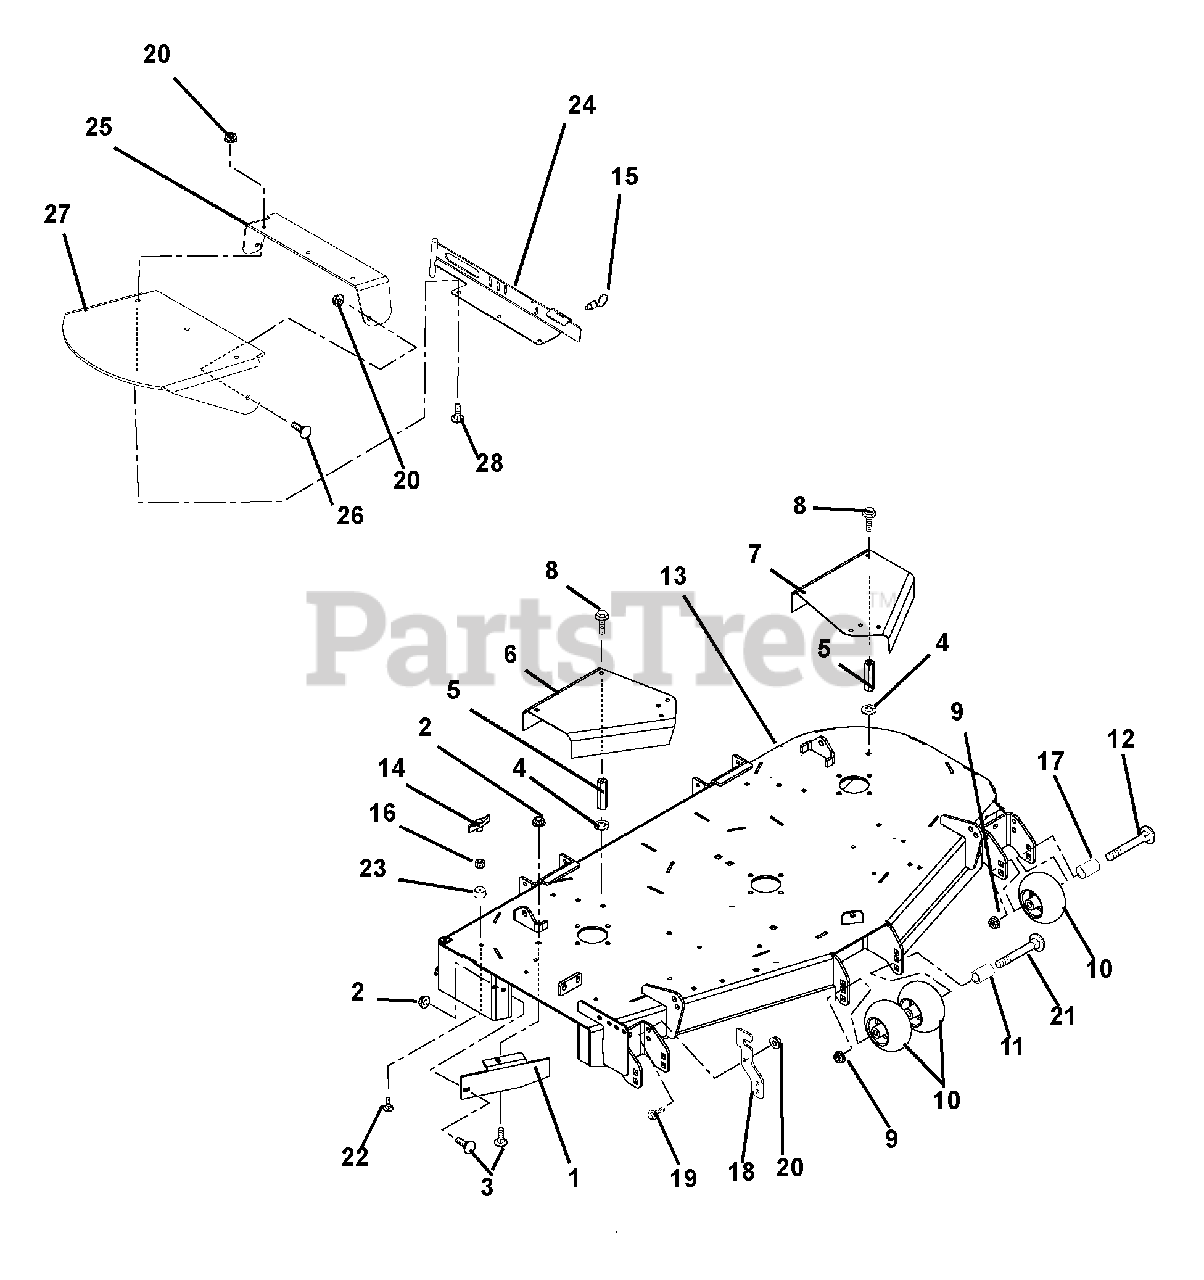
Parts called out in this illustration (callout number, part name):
1	52-in. Discharge Baffle
1	60-in. Discharge Baffle
1	72-in. Discharge Baffle
2	Nut, .31-18 Nyloc Flange
3	Bolt, Round Head Square Neck .31-18 x 1.00 Grade 5
4	Washer, Lock Internal .375
5	Standoff, .38-16 x .50 Self Tapping
6	52-in. Right Hand Spindle Guard
6	60-in. Right Hand Spindle Guard
6	72-in. Right Hand Spindle Guard
7	52-in. Left Hand Spindle Guard
7	60-in. Left Hand Spindle Guard
7	72-in. Left Hand Spindle Guard
8	Bolt, SEMS .31-18 x .62
9	Nut .50-13 Nyloc Flange
10	Anti-Scalp Wheel
12	Bolt-Round Head Square Neck .50-13X5.00
13	52-in. Mower Deck
13	60-in. Mower Deck
13	72-in. Mower Deck
14	Knob, Wing .312-18
15	Pin, Plunger Pull .50-13 Thread x .310 Diameter
16	Nut, Locking, Center .31-18
17	Spacer, .510 x .625 x 3.35
18	Chute, Storage Bracket
19	Bolt, Hex .38-16 x 1.00
20	Nut, .38-16 Nyloc Flange
21	Bolt, Round Head Square Neck .50-13 x 8.50
22	Bolt, Round Head Square Neck .31-18 x 1.50
23	Bumper, Recessed 1.50 x .63 , .31 Thru Hole
24	52-inch and 60-inch Discarch Chute Mounting Weldment
24	72-inch Discharge Chute Mounting Weldment
25	Rubber Discharge Chute Support
26	Bolt, Round Head Square Neck .38-16 x 1.00 Grade 5
27	Chute, Rubber Discharge
28	Bolt, Round Head Square Neck .38-16 x 1.25 Grade 5
